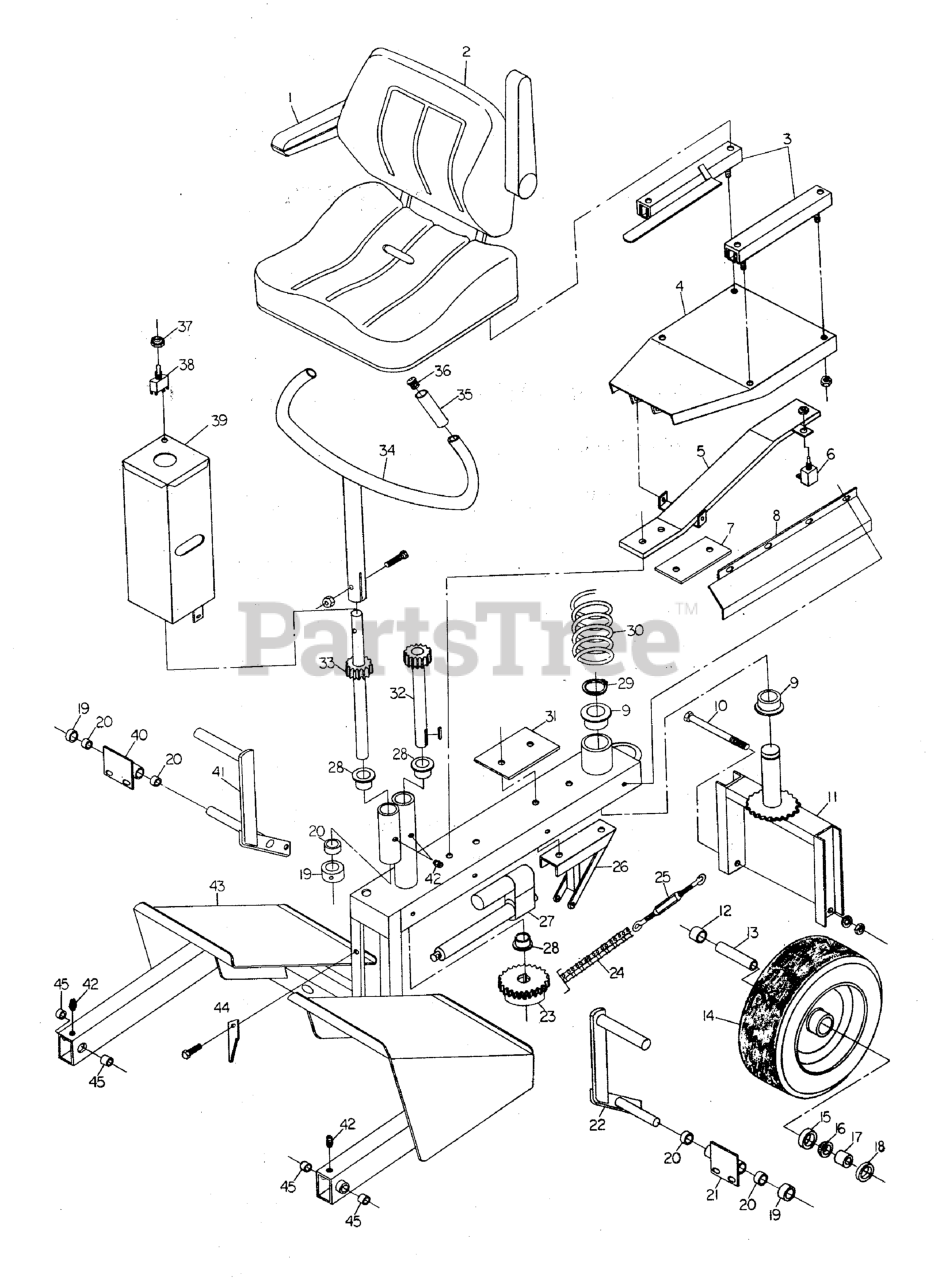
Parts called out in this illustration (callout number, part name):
1	Arm Rest (Left/Right Interchangeable)
2	Seat Assembly
3	SEAT ADJUSTER RAILS (Set)
4	Seat Mounting Plate Weldment
5	Seat Spring Weldment
6	Seat Switch
7	SUPPORT, Seat Plate
8	Chain Guard Left
9	BUSHING, Flange
10	BOLT, 5/8-11 x 9-1/2
11	Steering Wheel Mount Weldment
12	SPACER, 1.00 x 1.25 x 1.53
13	Steering Wheel Sleeve
14	Steering Tire Assembly
14	Tire Only
14	Rim Only
15	BEARING CUP
16	BEARING, Tapered Roller
17	Steering Tire Spacer
18	GREASE SEAL
19	COLLAR, 3/4" Set
20	BUSHING, Brass
21	Clutch Pedal Bracket Weldment
22	Clutch Pedal Weldment
23	40B 24 x 3/4 Sprocket
24	CHAIN, #40 Roller, 99 Links
25	Turnbuckle
26	Actuator Mount Weldment
27	Electric Actuator
28	BUSHING, Flange
29	SNAP RING, External
30	Compression Seat Spring
31	Actuator Mount Support
32	Steering Shaft Weldment
33	Steering Handle Shaft Weldment
34	Steering Handle Weldment
35	GRIP, Foam
36	End Plug
37	Toggle Boot
38	Toggle Switch
39	Steering Gear Guard
40	Brake Pedal Bracket
41	Brake Pedal Weldment
42	GREASE FITTING
43	Rider Frame Weldment
44	Brake Lever
45	BUSHING
